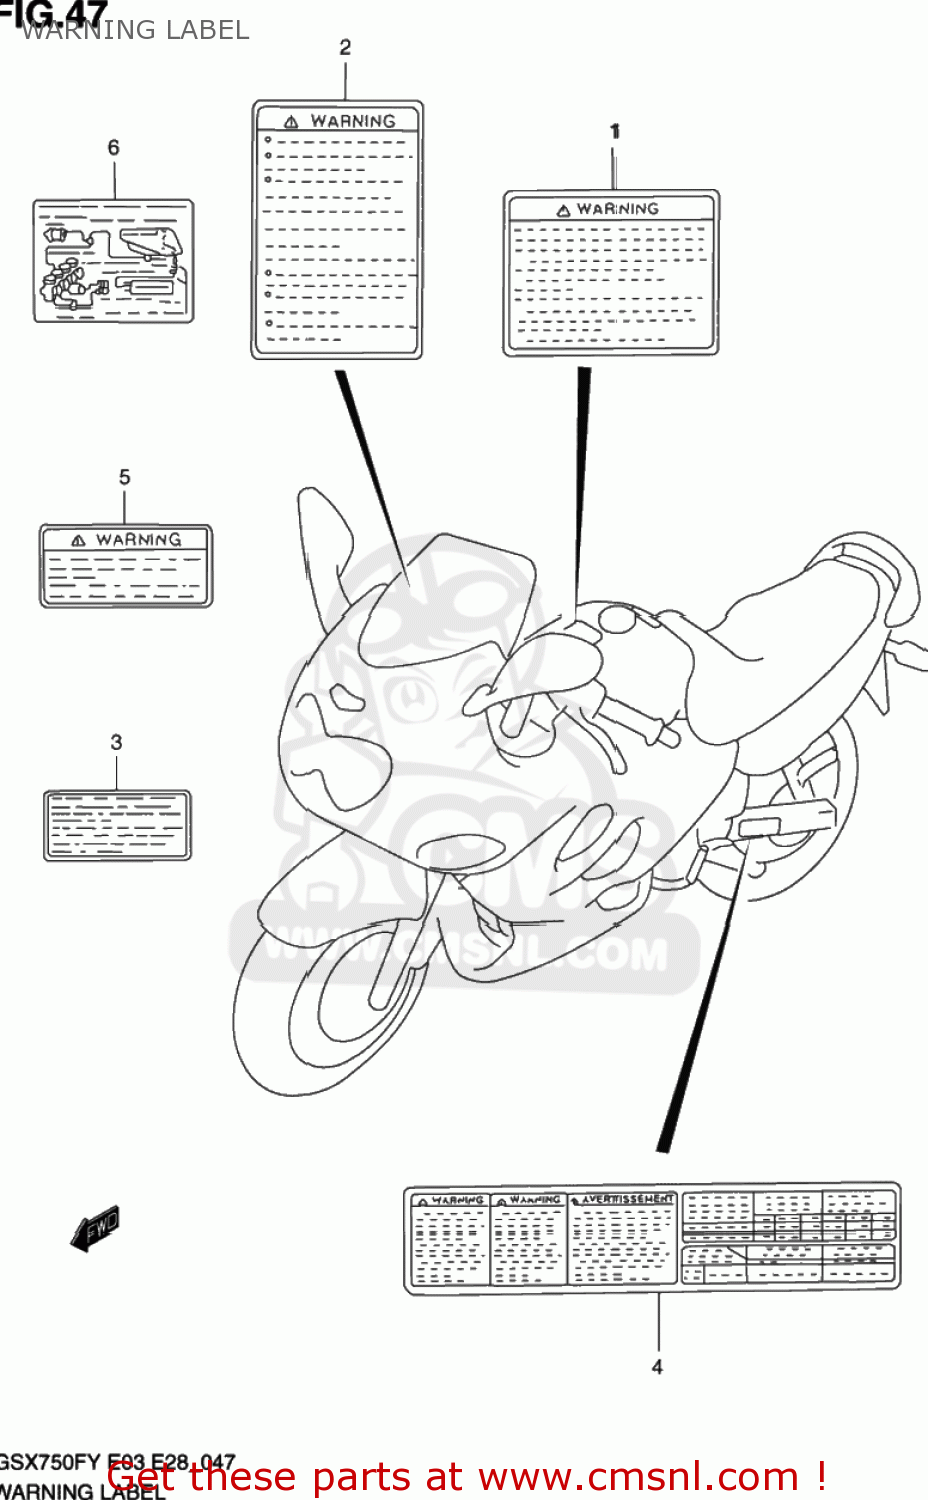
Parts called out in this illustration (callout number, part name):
1	LABEL,GENERAL WARNING
2	LABEL,SCREEN
3	LABEL,MANUAL NOTICE
4	LABEL, TIRE INFORMATION
5	LABEL,WARNING STEERING
6	LABEL,VACUUM HOSE ROUTING
7	MANUAL,OWNER'S
